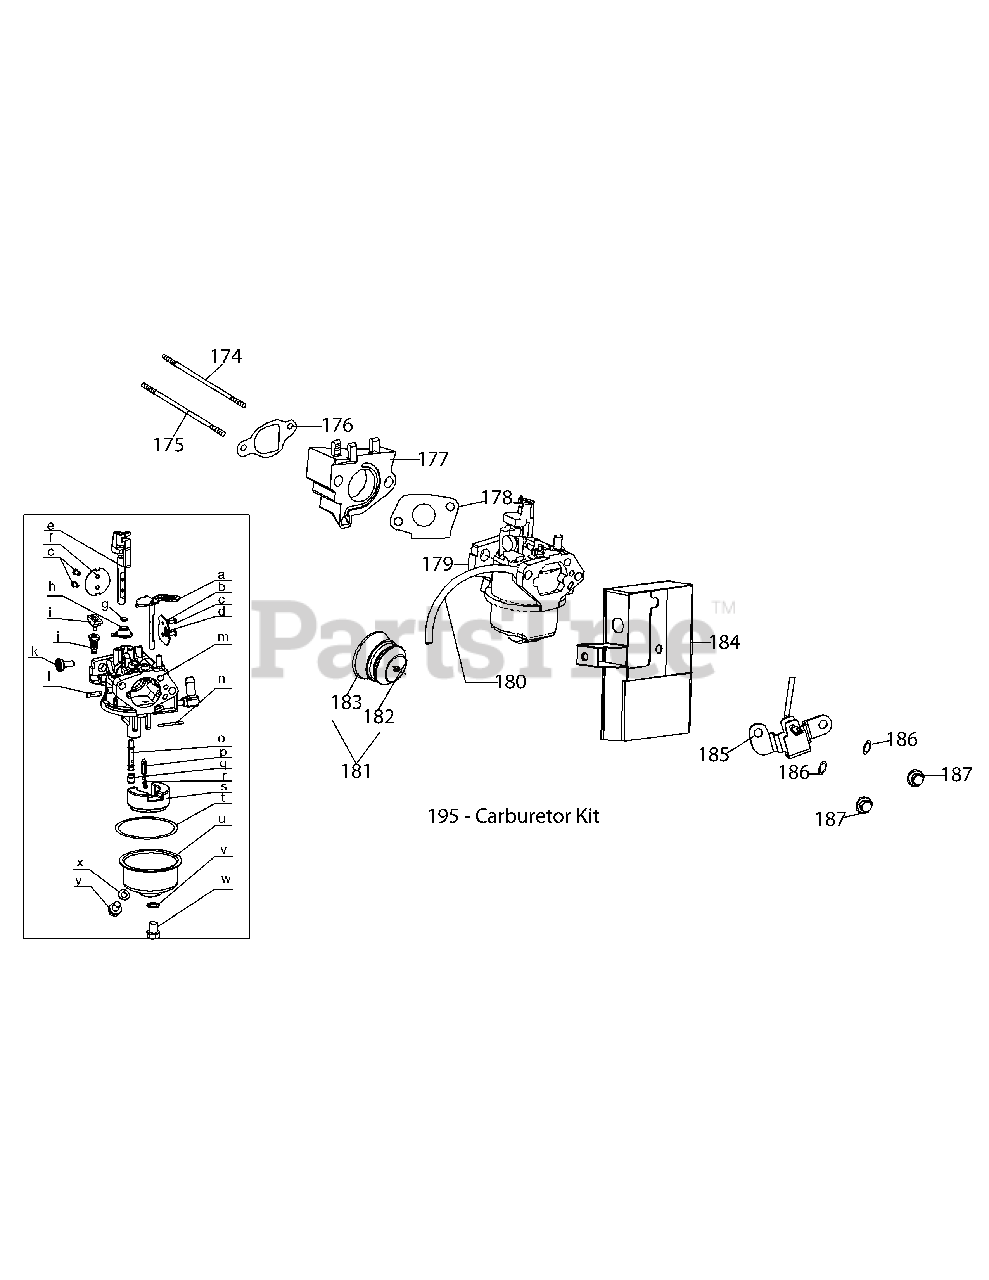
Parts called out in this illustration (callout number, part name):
174	Stud M6-8×100
175	Stud M6-8×118
176	Carburetor Insulator Gasket
177	Carburetor Insulator
178	Carburetor Gasket
179	Carburetor Assembly
180	Primer Hose
181	Primer Assembly
182	Primer Bulb
183	Primer Hose Clamp
184	Heater Box
185	Choke Control
186	Lock Washer
195	Carburetor Kit
